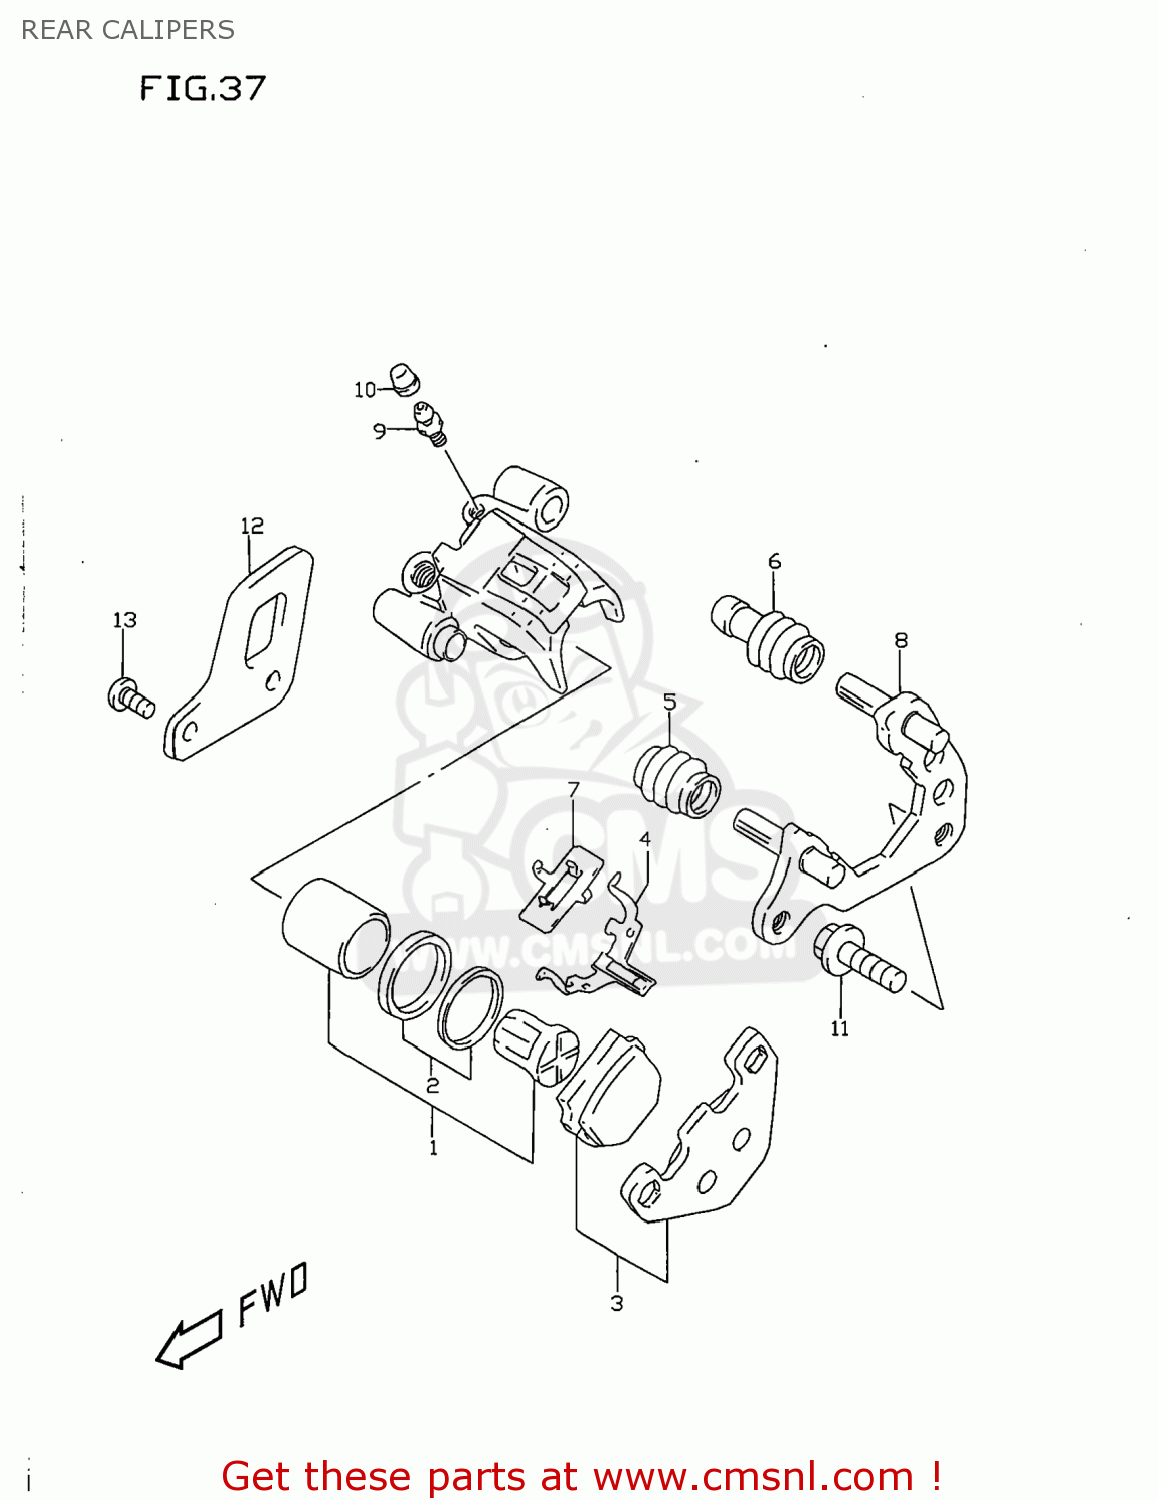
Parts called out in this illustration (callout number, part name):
1	PISTON SET
2	SEAL SET,PISTON
3	PAD SET (NAS)
4	SPRING,PAD
5	BOOT,AXLE
6	INSULATOR,AXLE
7	SHIM
8	CARRIER,CALIPER
9	BLEEDER
10	CAP,BLEEDER PLUG
11	BOLT(8X18)
12	GUARD,RR CALIPER
13	SCREW(6X12)
